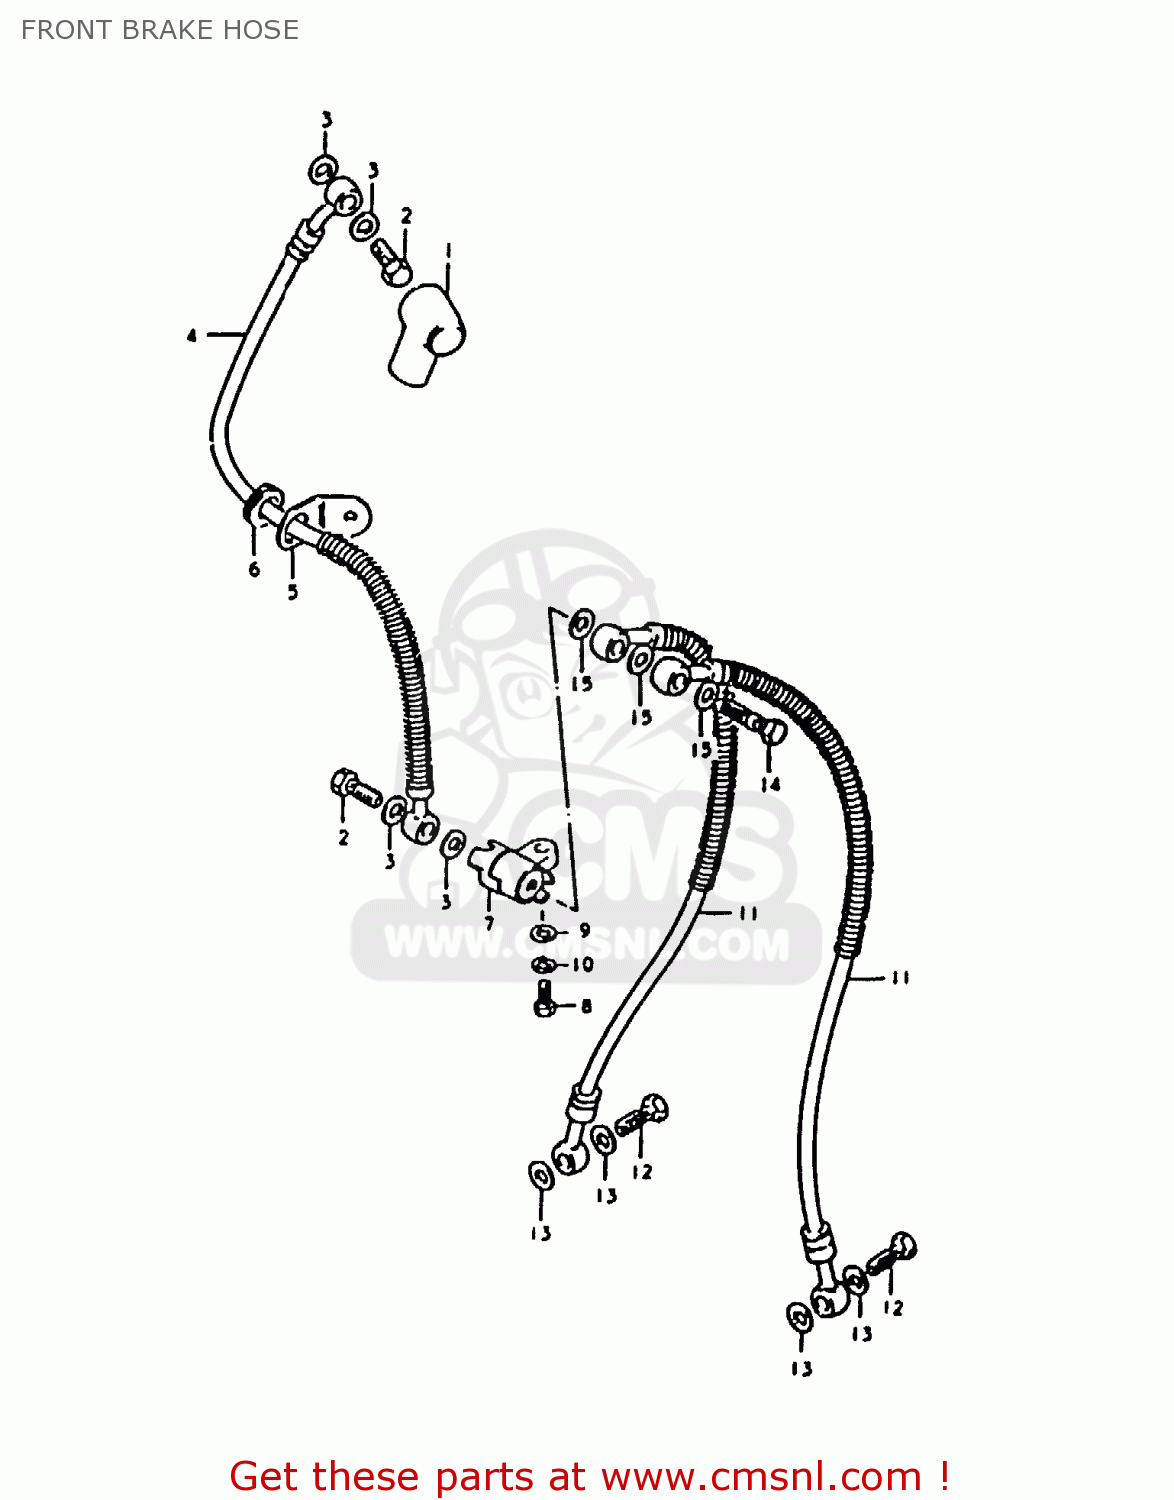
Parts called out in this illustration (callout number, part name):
1	BOOT
2	BOLT UNION
3	WASHER
4	HOSE,FRONT BRAKE
5	GUIDE,BRAKE HOSE
6	GROMMET
7	JOINT,BRAKE HOSE
8	BOLT
9	WASHER
10	LOCK WASHER
11	HOSE,FRONT BRAKE
12	BOLT UNION
13	WASHER
14	BOLT UNION
15	WASHER
